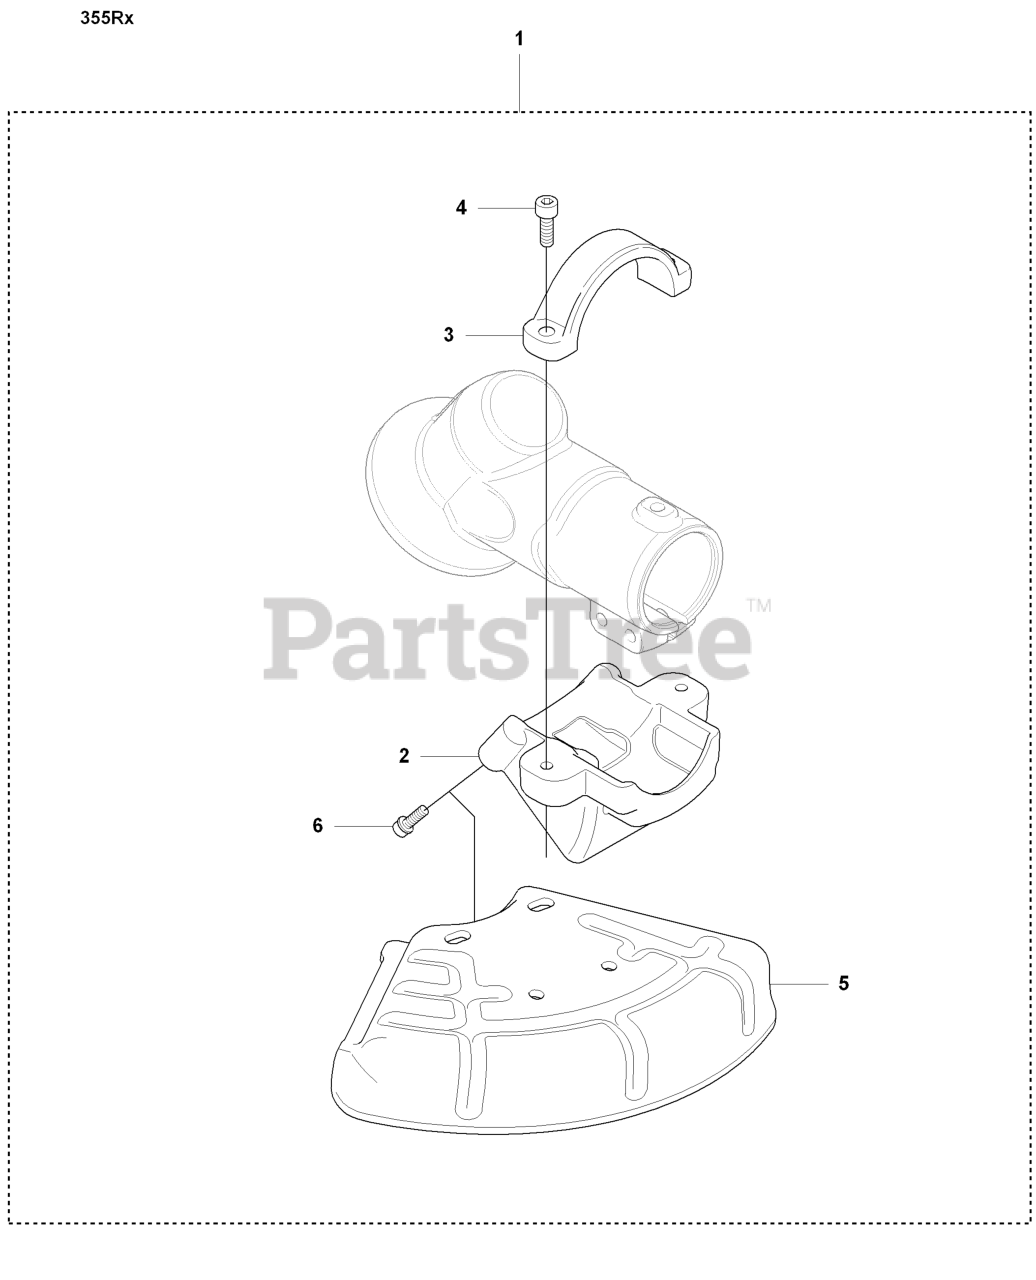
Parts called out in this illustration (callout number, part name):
2	BLADE GUARD SAW
5	BLADE GUARD SAW
6	SCREW IHSCFM
